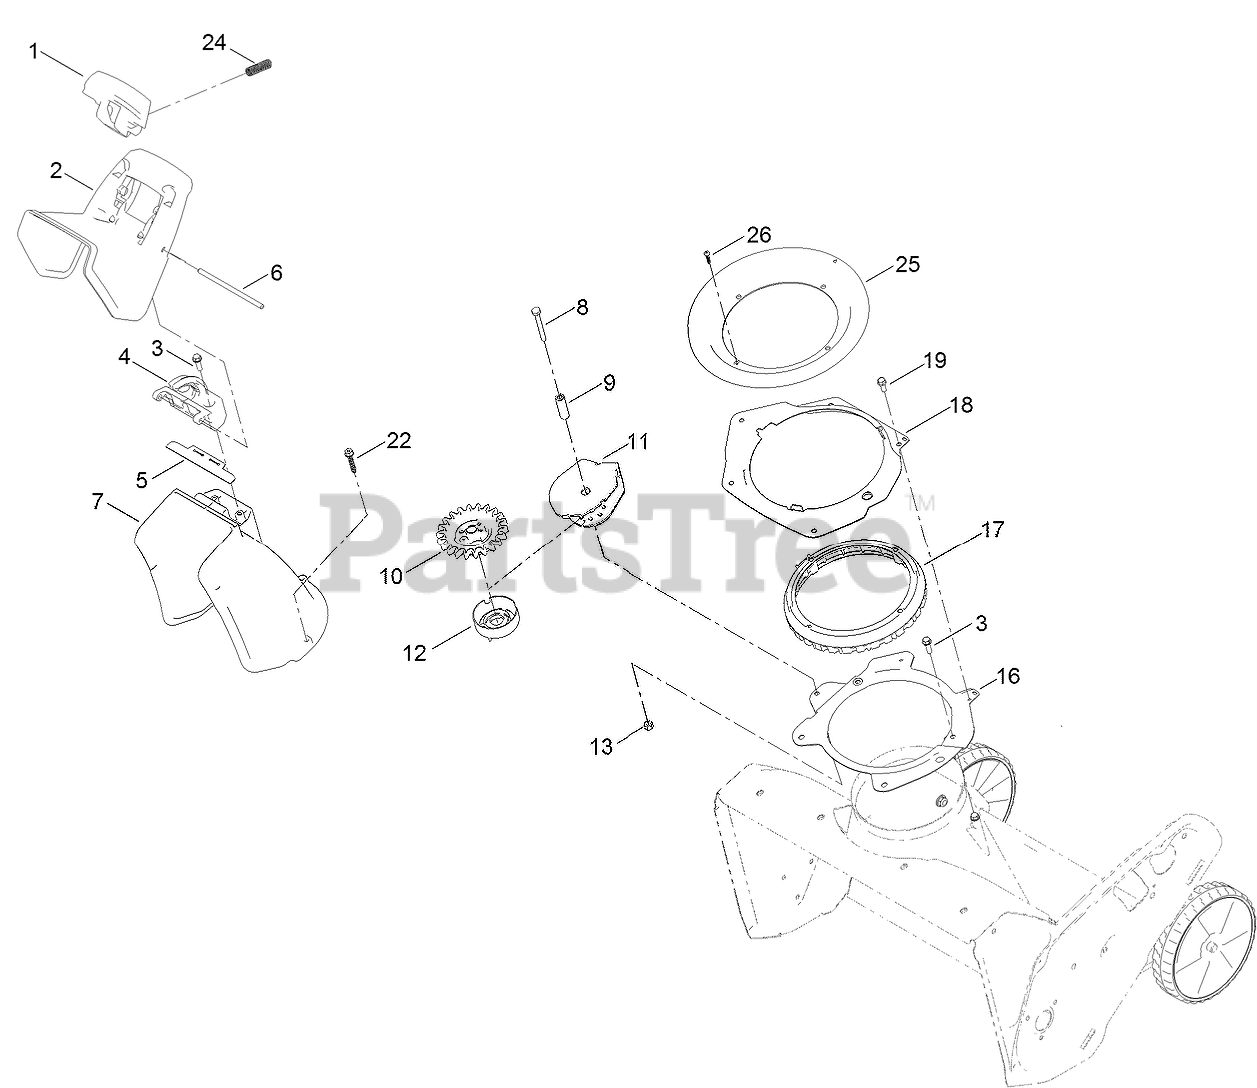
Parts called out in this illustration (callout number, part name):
1	TRIGGER-DEFLECTOR
2	DEFLECTOR-CHUTE, CE
3	SCREW-PLASTITE, HWH
4	HINGE-RATCHET, DEFLECTOR
5	SEAL-DEFLECTOR
6	HINGE PIN-DEFLECTOR
8	SCREW-HH
9	SPACER-SLEEVE, PINION
10	PINION-GEAR
11	BRACKET-PINION
12	RETAINER-CABLE
13	NUT-HEX
16	RING-SUPPORT, CHUTE
17	RING-CHUTE, GEAR
18	RETAINER-RING, CHUTE
19	SCREW-HWH
22	SCREW-PLASTITE, HWH
24	SPRING-COMPRESSION
25	SEAL-RING, CHUTE
26	SCREW-PPH
